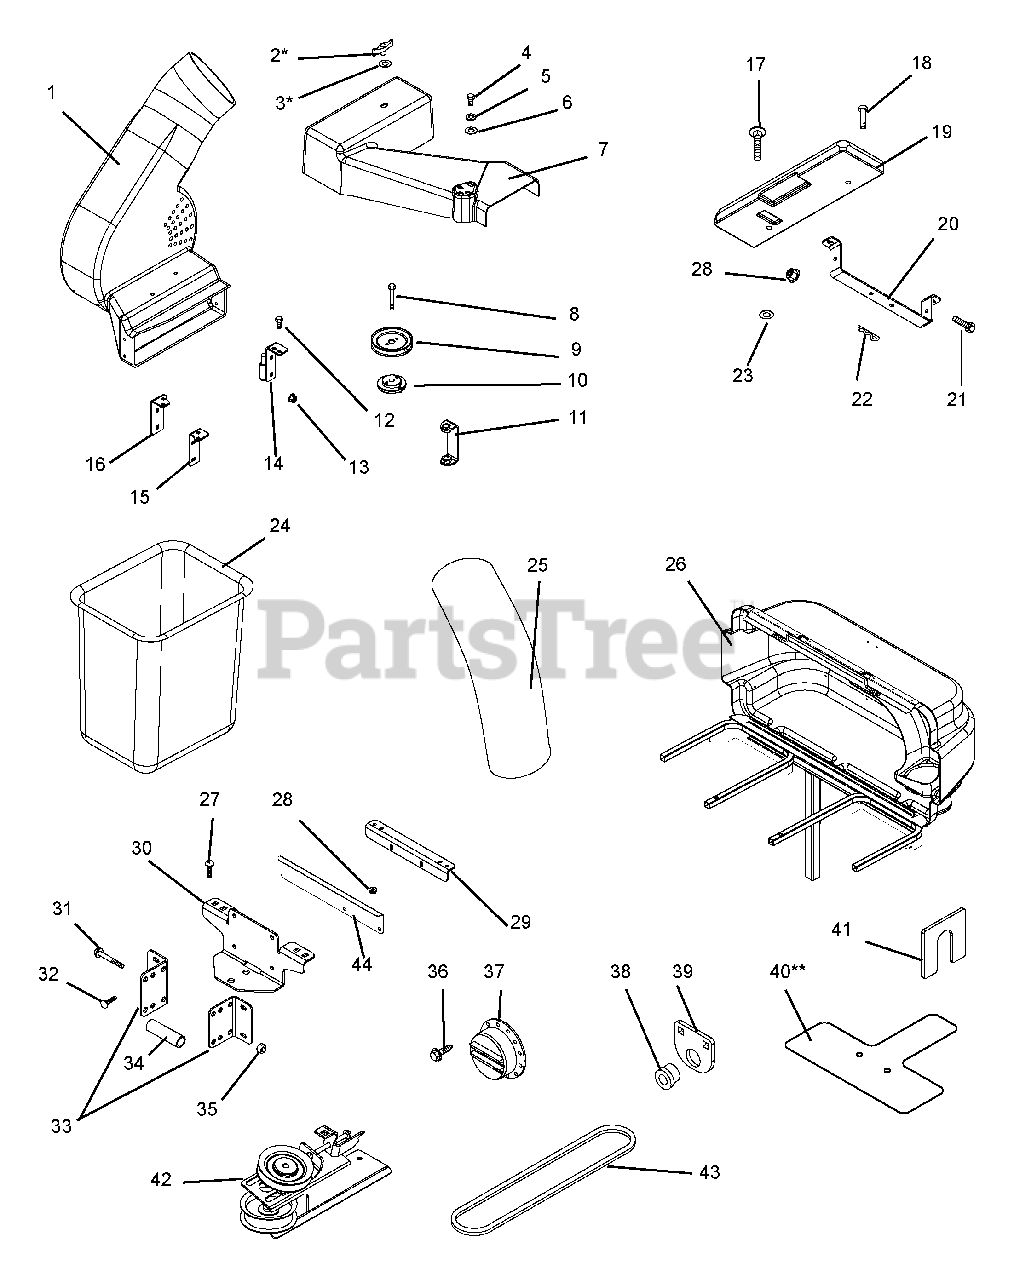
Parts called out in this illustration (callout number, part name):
1	BLOWER (SERVICE ASSEMBLY)
2	KNOB - WING .312-18 UNC
3	WSHR-FL-STL .380X1.50X.062 YWZ
4	@BLT-HEX .38-16X.75 GR5 YWZC
5	@WSHR-LK .38X.094 REG YWZC
6	@WSHR-FL-STL.438X1.00X.083 YWZ
7	BELT COVER W/DECAL
8	BLT-HEX .38-16X1.75 GR8 M-EPYZ
9	SHEAVE, 3.00 DIA.
9	SHEAVE, 4.00 DIA.
10	ASSEMBLY, SHEAVE ADAPTER
11	SPACER, COVER
12	@BLT-HEX .25-20X.75 GR5 YWZC
13	@NUT-LK-TOP-FLG .25-20 YWZC
14	WELDMENT, REAR MOUNT BRACKET
15	BRACKET, FRONT
16	WELDMENT, FRONT MOUNT BRACKET
17	@BLT-RDHDSQNK .38-16X1.00 G5YZ
18	PIN-CLEV .494X2.50 BRIGHT ZINC
19	WEIGHT, CAST IRON
20	BRACKET,WEIGHT
21	@BLT-HEX .38-16X1.00 GR5 YWZC
22	PIN-HAIR-EXT .12X.31X2.37 YWZC
23	WSHR-FL-STL .515X1.625X.250 YZ
24	GRASS BAGGER BASKET
25	HOSE,7X45 KANAFLEX 165CL
26	Cover Assembly
27	@BLT-RDHDSQNK .38-16X2.50 G5YZ
28	@NUT-LK-TOP-FLG .38-16 YWZC
29	BRKT,ANGLE
30	TRAILER HITCH W/DECALS
31	@BLT-HEX .50-13X3.00 GR5 YWZC
32	@BLT-RDHDSQNK .38-16X1.25 G5YZ
33	BKT,BAGGER MOUNT
34	SPACER, PIVOT .500X.750X1.805
35	@NUT-LK-TOP-FLG .50-13 YWZC
36	SCR-TAP 8-32X.38 SL HWH YWZC
37	DEFLECTOR,EXHAUST
38	BSHG-FLG 1.000X1.12X.62X1.50BR
39	BRACKET,REAR PIVOT
40	GUARD,FINGER
41	PLATE,LIFT
42	Idler Assembly
43	V-BELT, HA-WRAPPED
43	V-BELT, HA-RAW EDGE
44	DEFLECTOR, EXHAUST
